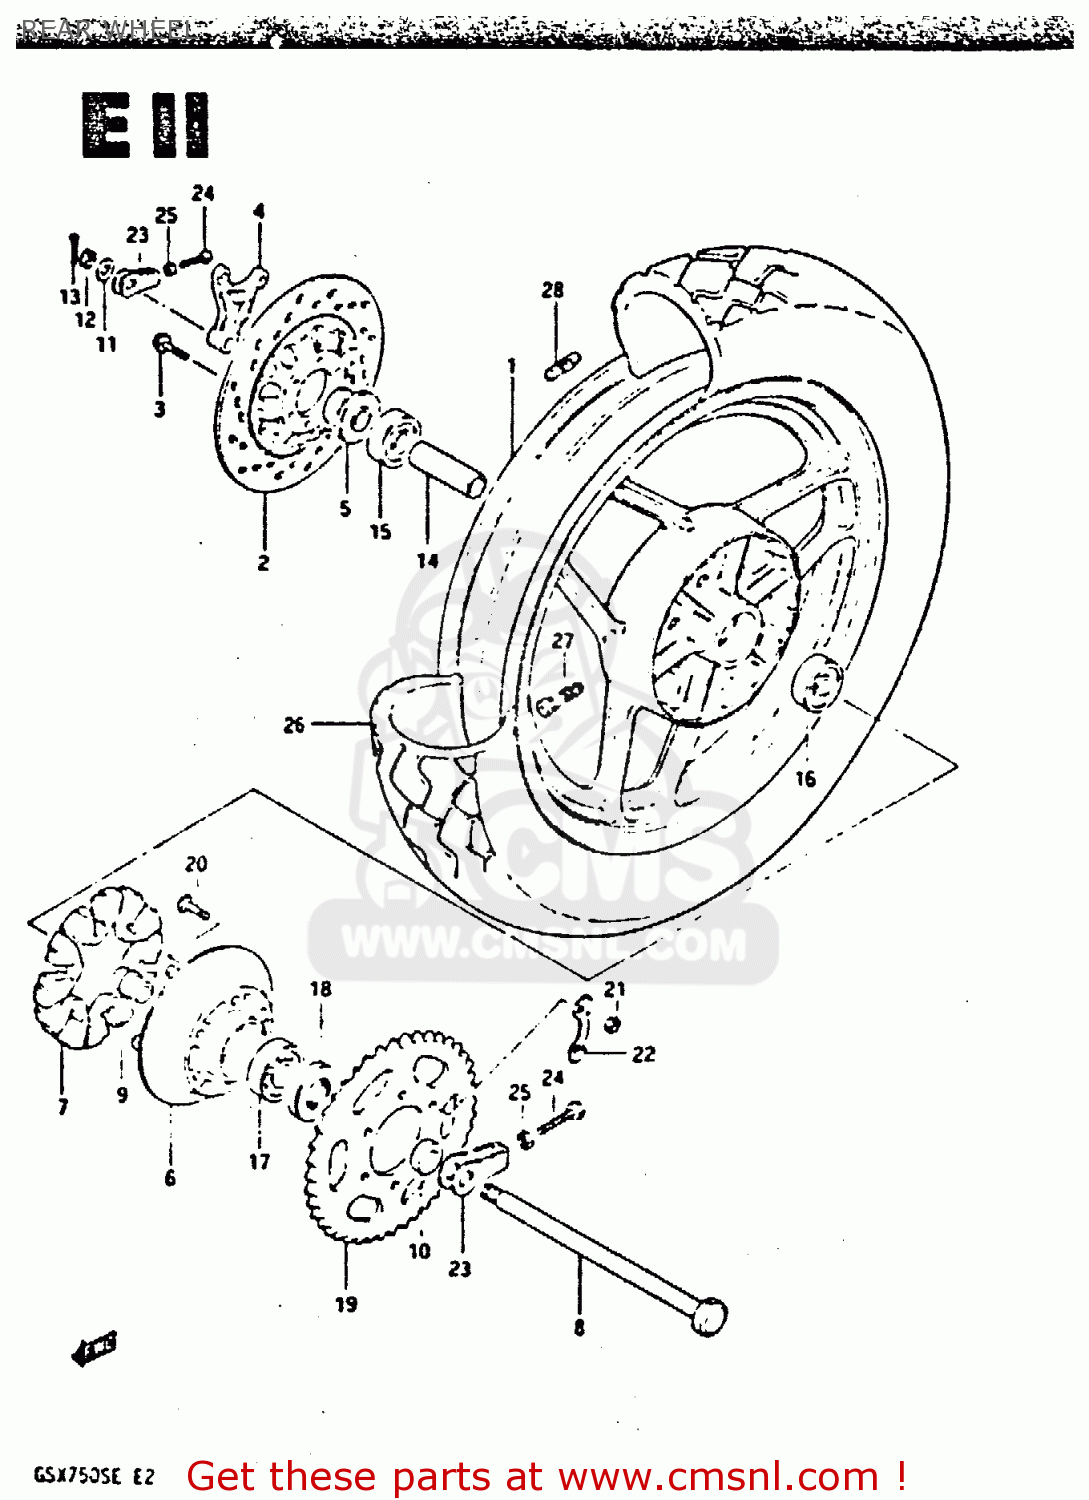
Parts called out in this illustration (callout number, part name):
1	WHEEL, REAR (17*MT2.5) GOLD
2	DISC,BRAKE
3	BOLT
4	BRACKET,REAR CALIPER
5	SPACER,REAR AXLE
6	DRUM,REAR SPROCKET MOUNT
7	ABSORBER,REAR HUB SHOCK
8	AXLE,REAR
9	RETAINER,RR SPROCKET DRUM
10	SPACER(17X33X11.3)
11	WASHER
12	NUT
13	PIN,COTTER
14	SPACER(17.5X25X88)
15	BEARING
16	BEARING
17	BEARING
18	SEAL,OIL(33X62X7)
19	SPROCKET, REAR (NT:43)
20	BOLT
21	NUT
22	WASHER
23	ADJUSTER, CHAIN
24	BOLT
25	NUT
26	TIRE, T/L REAR (120/90-17 64H)
27	VALVE,TIRE
28	BALANCER (10G) GOLD
